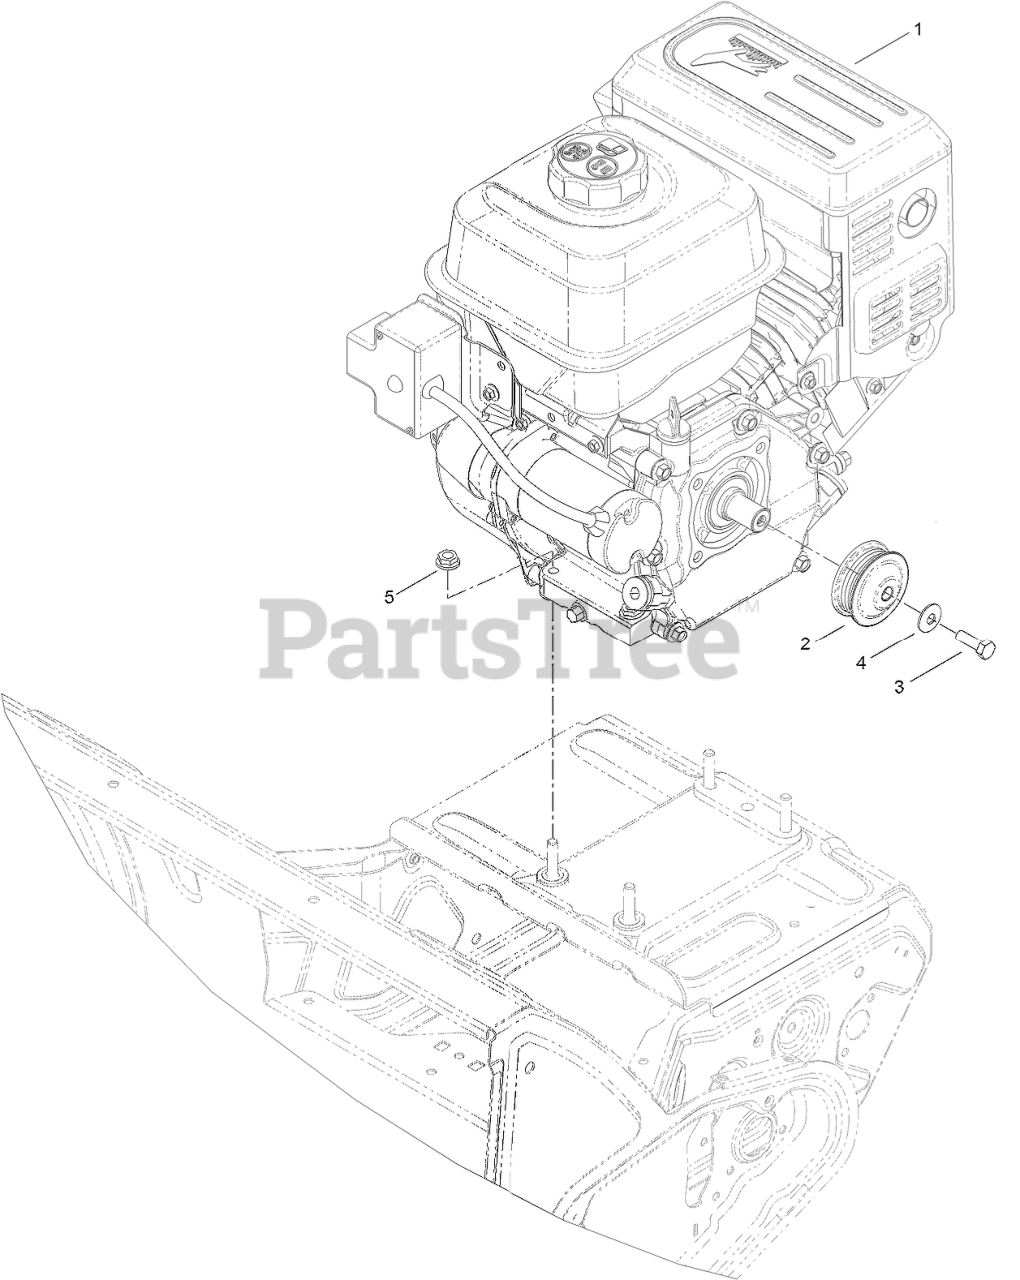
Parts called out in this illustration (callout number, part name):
1	ENGINE-G210FDS-2
2	PULLEY-ENGINE
3	SCREW-HH, PATCH
4	WASHER-BELLEVILLE
5	NUT-HF
